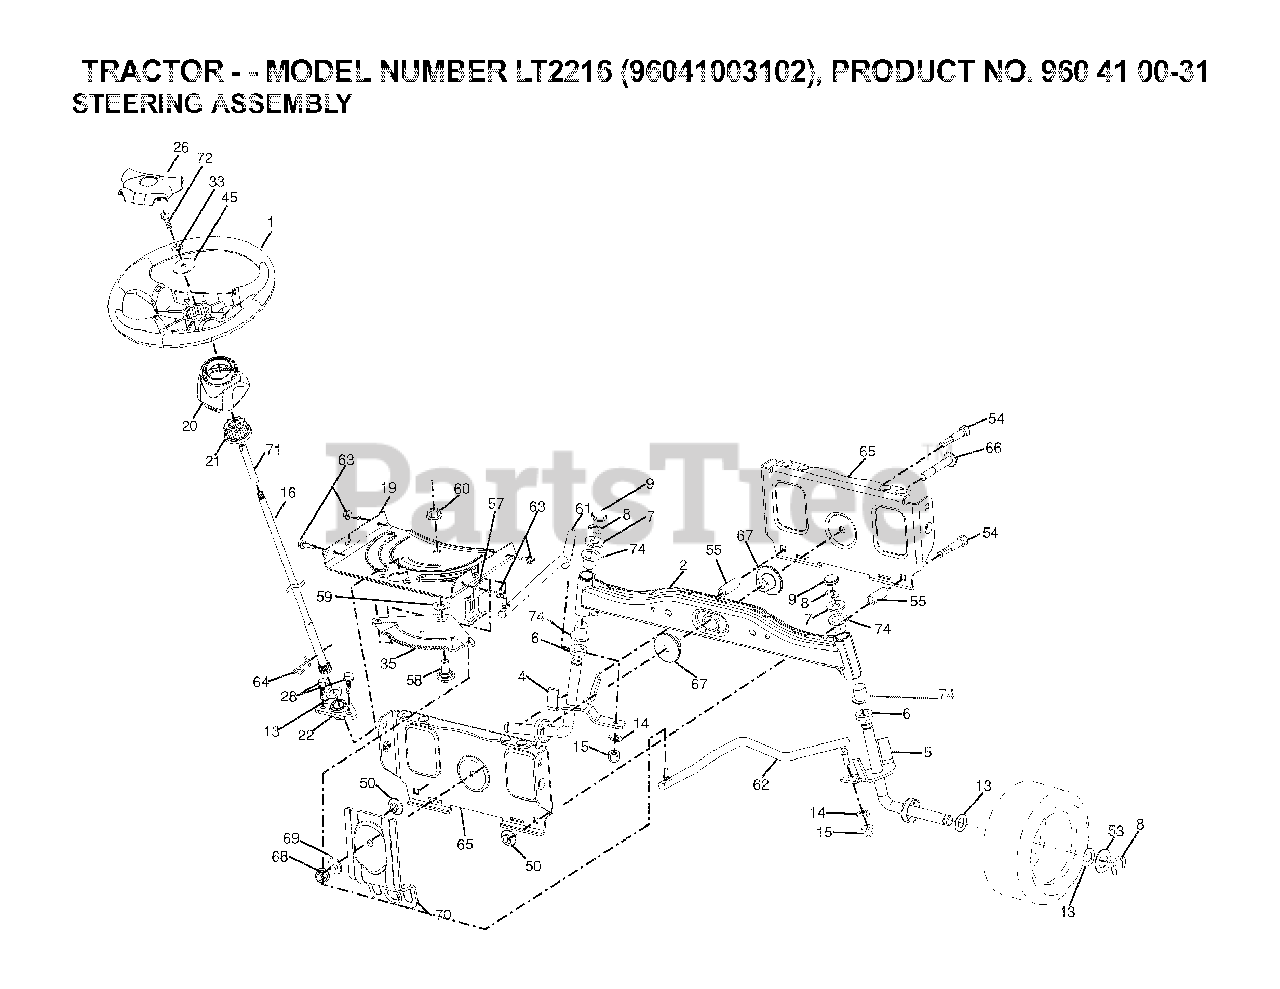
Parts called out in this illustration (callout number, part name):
2	AXLE.HALF.ASM.WELDED
4	SPINDLE.WELDED.LH.15"TEX
5	SPINDLE.WELDED.RH.15"T
8	RING CLIP
9	CAP.SPINDLE
14	WASHER, LOCK 3/8
15	NUT CROWNLOCK 3/8-24
16	SHAFT STEERING
19	PLATE.STEER.DDL.NLT/NG
20	BOOT STEERING BLACK
21	ADAPTER, WHEEL STNG..
22	BUSHING.ASM.STEERING.A
26	INSERT.CAP.STRG.WH.BLACK
28	SCREW, 3/8-16X3/4
33	LOCKWASHER
35	GEAR.SECTOR.PLATE.DDL.
45	WASHER.11/32
50	NUT LOCK FLG 3/8-16 UNC
53	WASHER.HARDENED
55	SPACER.BRACE.AXLE
57	BRACKET.UPSTOP.TEX
58	BOLT.SHOULDER.SECTOR.P
59	WASHER.THURST.SECTOR.S
60	NUT FLANGE LOCK 5/8-11
61	DRAGLINK.LH.BALLSTUD.D
62	DRAGLINK.RH.BALLSTUD.D
63	SCREW
64	RETAINER.CLIP.SPRING.S
65	BRACE.AXLE.FRONT.NLT/N
66	BOLT HEX FGHD 7/16-14 X 3 SERR
67	BUSHING.PM.FRONT AXLE
68	NUT.LOCK.FLANGE.7/16
69	WASHER.1.5X.505X.118
70	BRKT.DECK.SUSPENSION.F
71	SHAFT EXTENSION STEERING
72	BOLT YT
74	BRNG T
